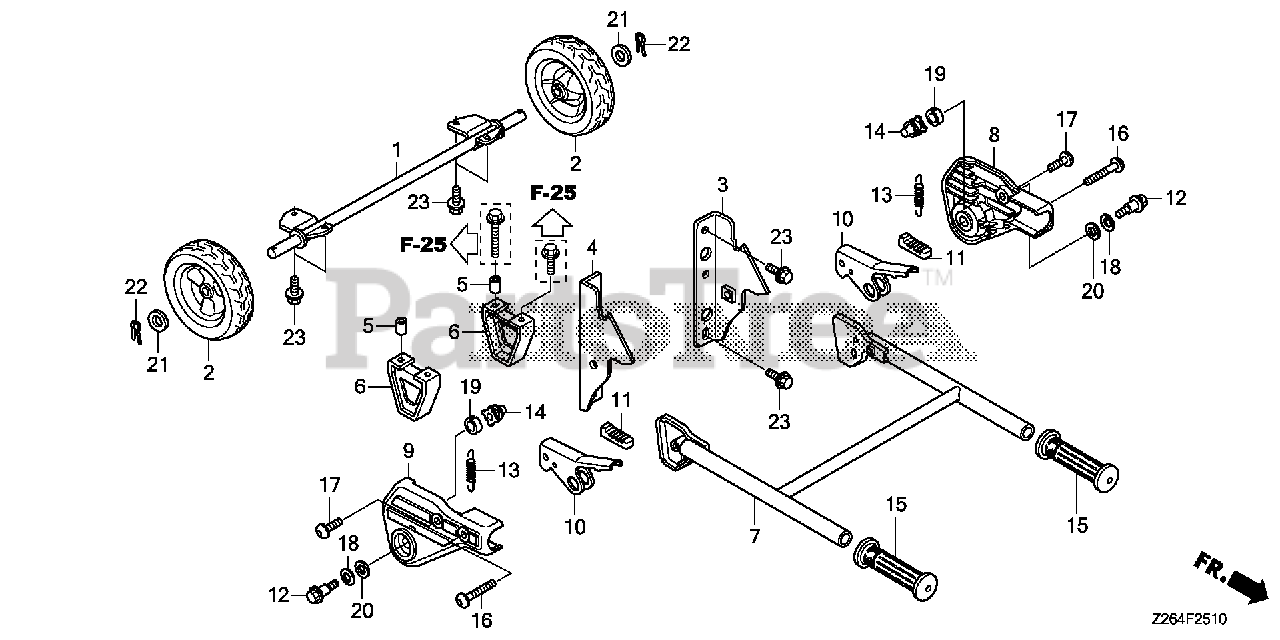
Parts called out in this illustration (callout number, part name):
1	SHAFT, WHEEL
2	WHEEL (254X75) (COO)(FOR U.S.A.)
3	BRACKET, R. HANDLE
4	BRACKET, L. HANDLE
5	COLLAR, STAND
6	STAND *NH105* (MAT BLACK)
7	PIPE, HANDLE *NH105* (COO)(FOR U.S.A.) (MAT BLACK)
8	HOLDER, R. HANDLE (COO)(FOR U.S.A.)
9	HOLDER, L. HANDLE (COO)(FOR U.S.A.)
10	LEVER, HANDLE
11	RUBBER, GRIP
12	BOLT, HANDLE HOLDER
13	SPRING, HANDLE LEVER
14	RUBBER, STOPPER
15	GRIP, HANDLE (COO)(FOR U.S.A.)
16	BOLT, SOCKET (8X43)
17	BOLT, SOCKET (8X22)
18	WASHER, SPRING
19	COLLAR, HANDLE
20	WASHER, PLAIN (12MM)
21	WASHER, PLAIN (20MM)
22	PIN, SPLIT (4.0X28)
22	PIN, SPLIT (4.0X30)
23	BOLT, FLANGE (8X16)
